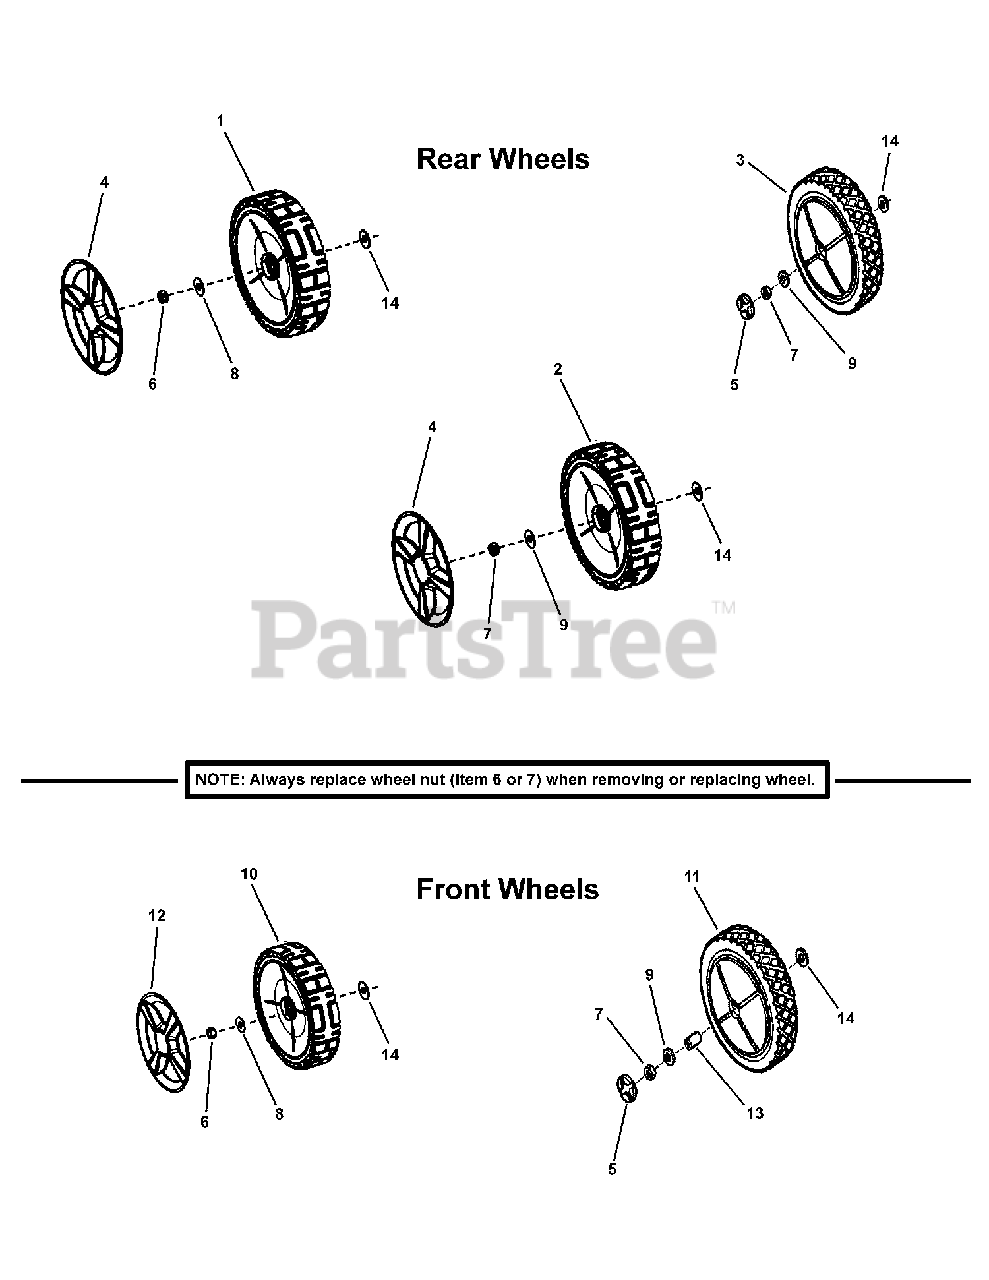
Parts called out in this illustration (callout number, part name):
1	ASSY, Wheel, 10 x 2" Idle, BB, Snapper Tread (push)
2	ASSY, Wheel, 10 x 2" Drive w/metal insert Snapper Tread
3	WHEEL, 10 x 1.75" Plastic (self-propelled)
4	HUBCAP, 10" Wheel, Spoked- Snapper Cool Gray
5	PLUG, Wheel
6	NUT, 3/8-16 Hex Center Lock
7	NUT, 7/16-20 Hex Center Lock Jam
8	WASHER, .387 x 1" O.O. Flat
9	WASHER, 7/16" Flat
10	ASSY, Wheel, 8 x 2" Idle, Snapper Tread, Charcoal Gray
11	WHEEL, 8 x 1.75" Plastic
12	HUBCAP, 8" Wheel, Spoked- Snapper Cool Gray
13	BUSHING, Axle
14	WASHER, Shim, .875 x .531 x .060
